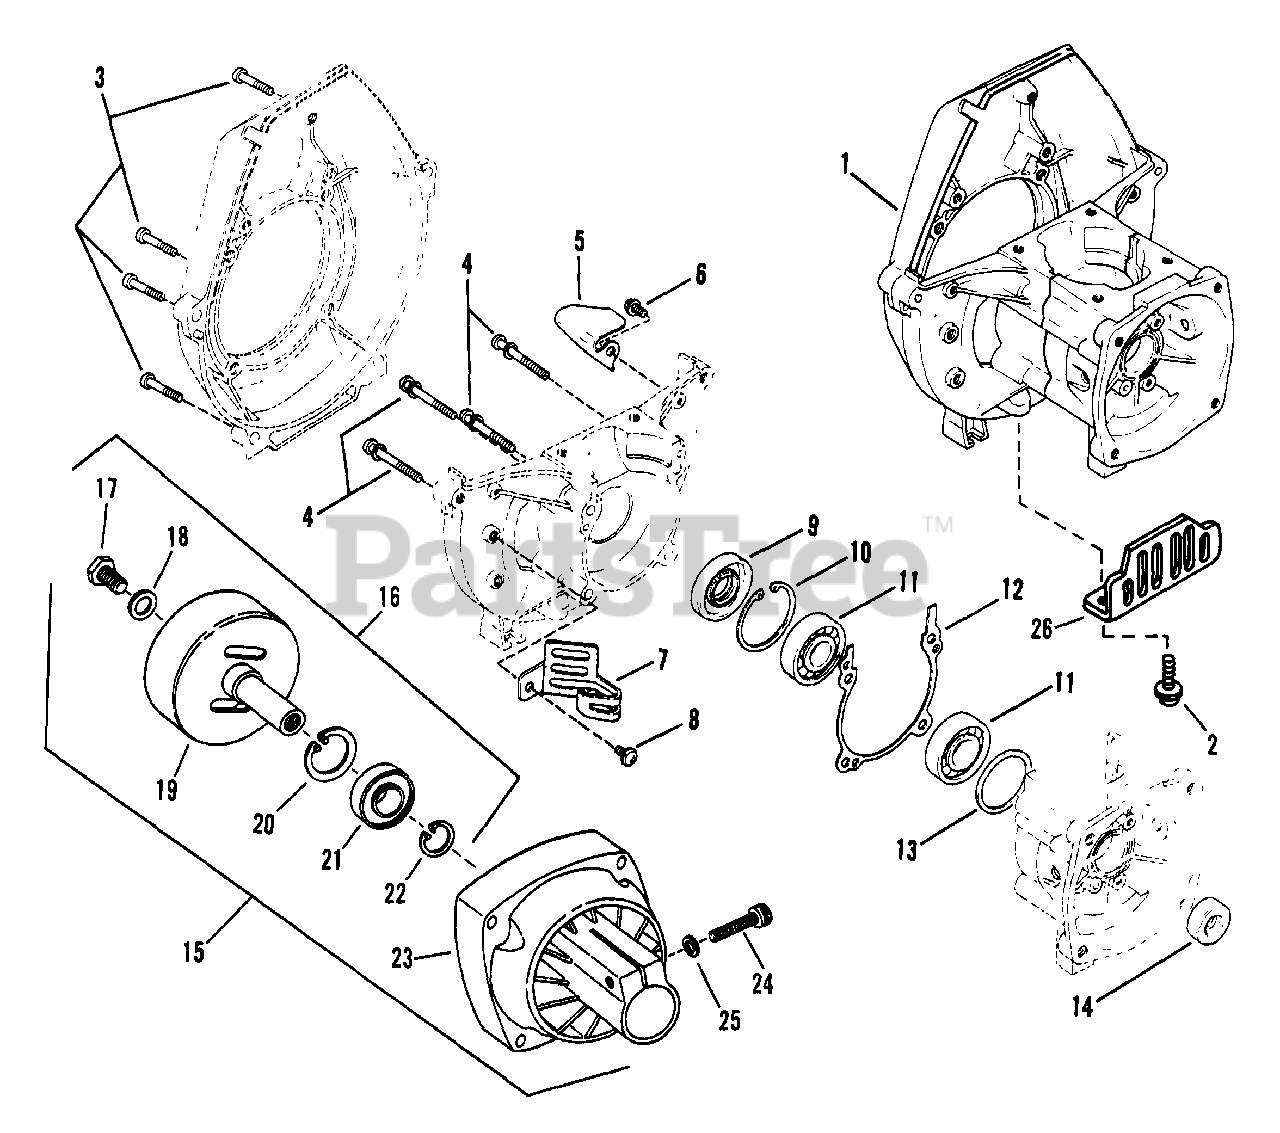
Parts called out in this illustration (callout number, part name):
1	CRANK CASE ASSM'Y
2	SCREW, M6x10mm Cross Hd.
9	SEAL, Oil
10	SNAP-RING
11	BEARING
12	GASKET, Crankcase
13	SHIM (Set of 3)
14	SEAL, Oil
15	ASSEMBLY, Clutch Case
16	ASSEMBLY,Clutch Drum
17	BOLT, Hex HD
19	DRUM, Clutch
20	RING, Snap
21	BEARING
22	RING, Snap
23	CASE, Clutch
24	SCREW, M6x25mm Socket
25	WASHER, M6 Split Lock
26	PLATE, Guard
